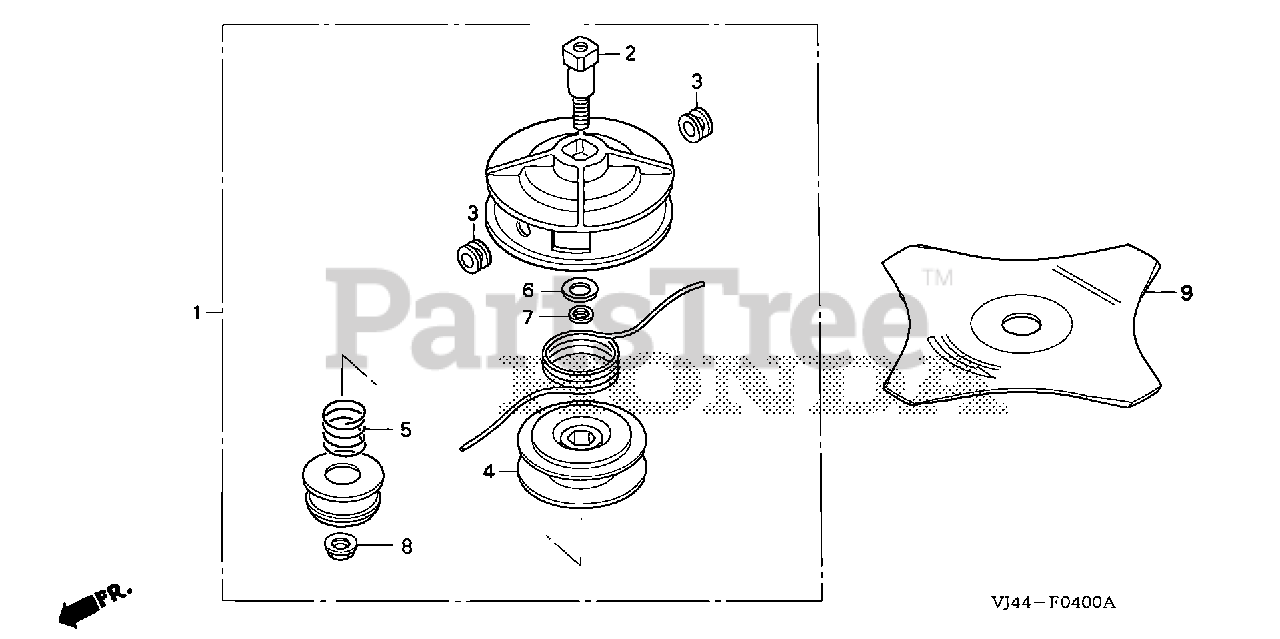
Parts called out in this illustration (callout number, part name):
1	CUTTER ASSY., NYLON
2	SHAFT, LHF (10X1.25)
5	SPRING
7	DRIVE (OUTER)
8	CAM (INNER)
